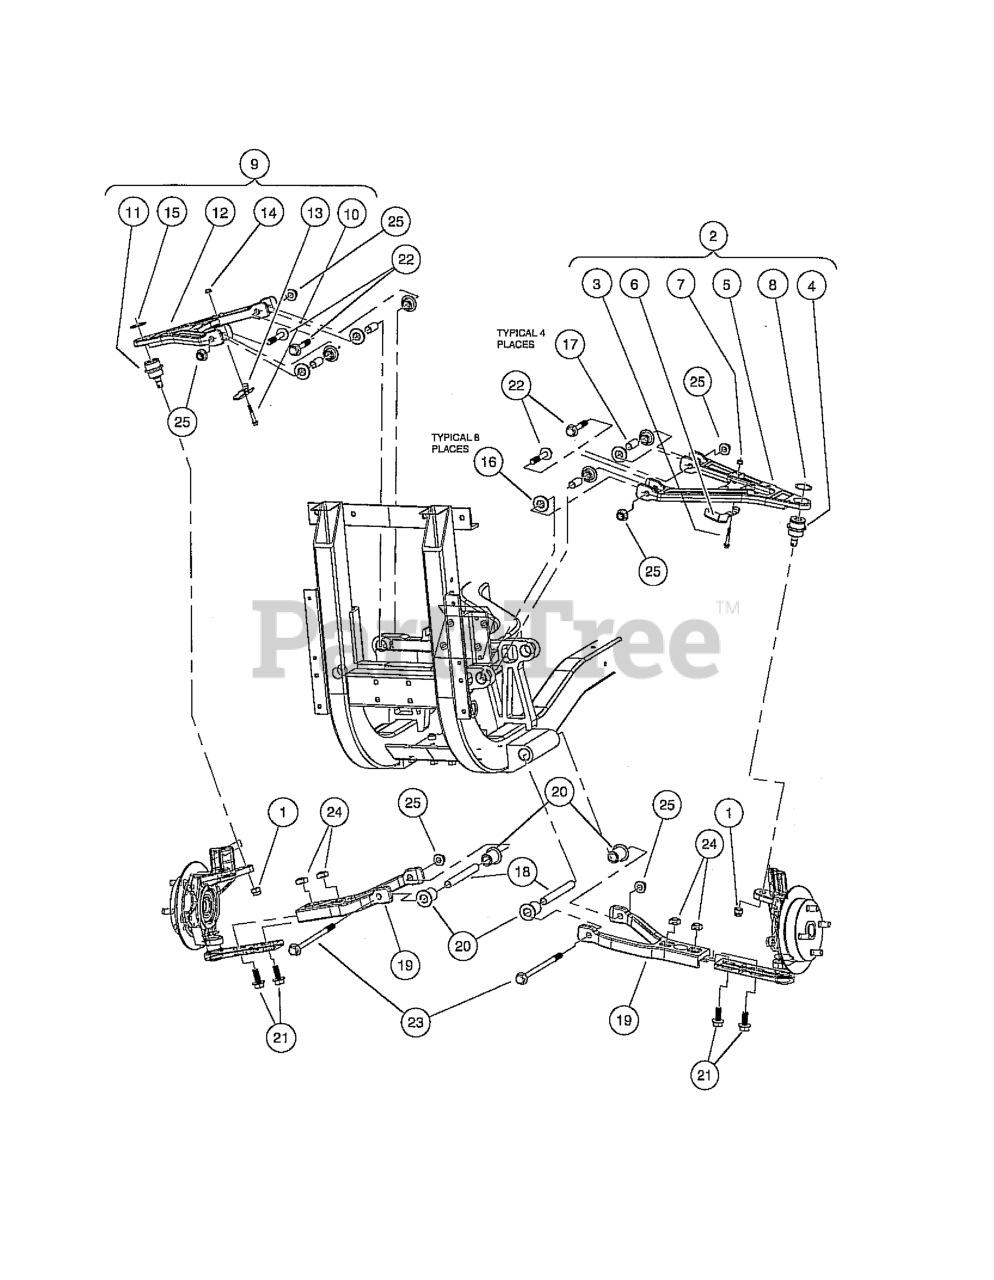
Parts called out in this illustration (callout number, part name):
1	LOCKNUT, M12-1.25 NYLON
2	SUB-ASSEMBLY, A-ARM, UPPER LH
3	BOLT - M6X1.0X40 HEX FLNG HD
4	BALL JOINT
5	A-ARM, UPPER, LEFT
6	BRACKET, BRAKELINE, LEFT
8	RING, RETAINING, EXT, 1-1/4"
9	SUB-ASSEMBLY,A-ARM, UPPER, RH
10	BOLT - M6X1.0X40 HEX FLNG HD
11	BALL JOINT
12	A-ARM, UPPER, RIGHT
13	BRACKET, BRAKELINE, RIGHT
15	RING, RETAINING, EXT, 1-1/4"
16	BUSHING, A-ARM
17	SLEEVE, UPPER
18	SLEEVE, LOWER
19	ARM, LOWER
20	BUSHING, LOWER ARM
21	BOLT, FLG, M12X1.75X30
22	BOLT, FLG, M12X1.75X70
23	BOLT, FLG, M12X1.75X200
24	NUT, SQUARE, M12 X 1.75
25	NUT FLG, M12X1.75, NYLON GR 10
